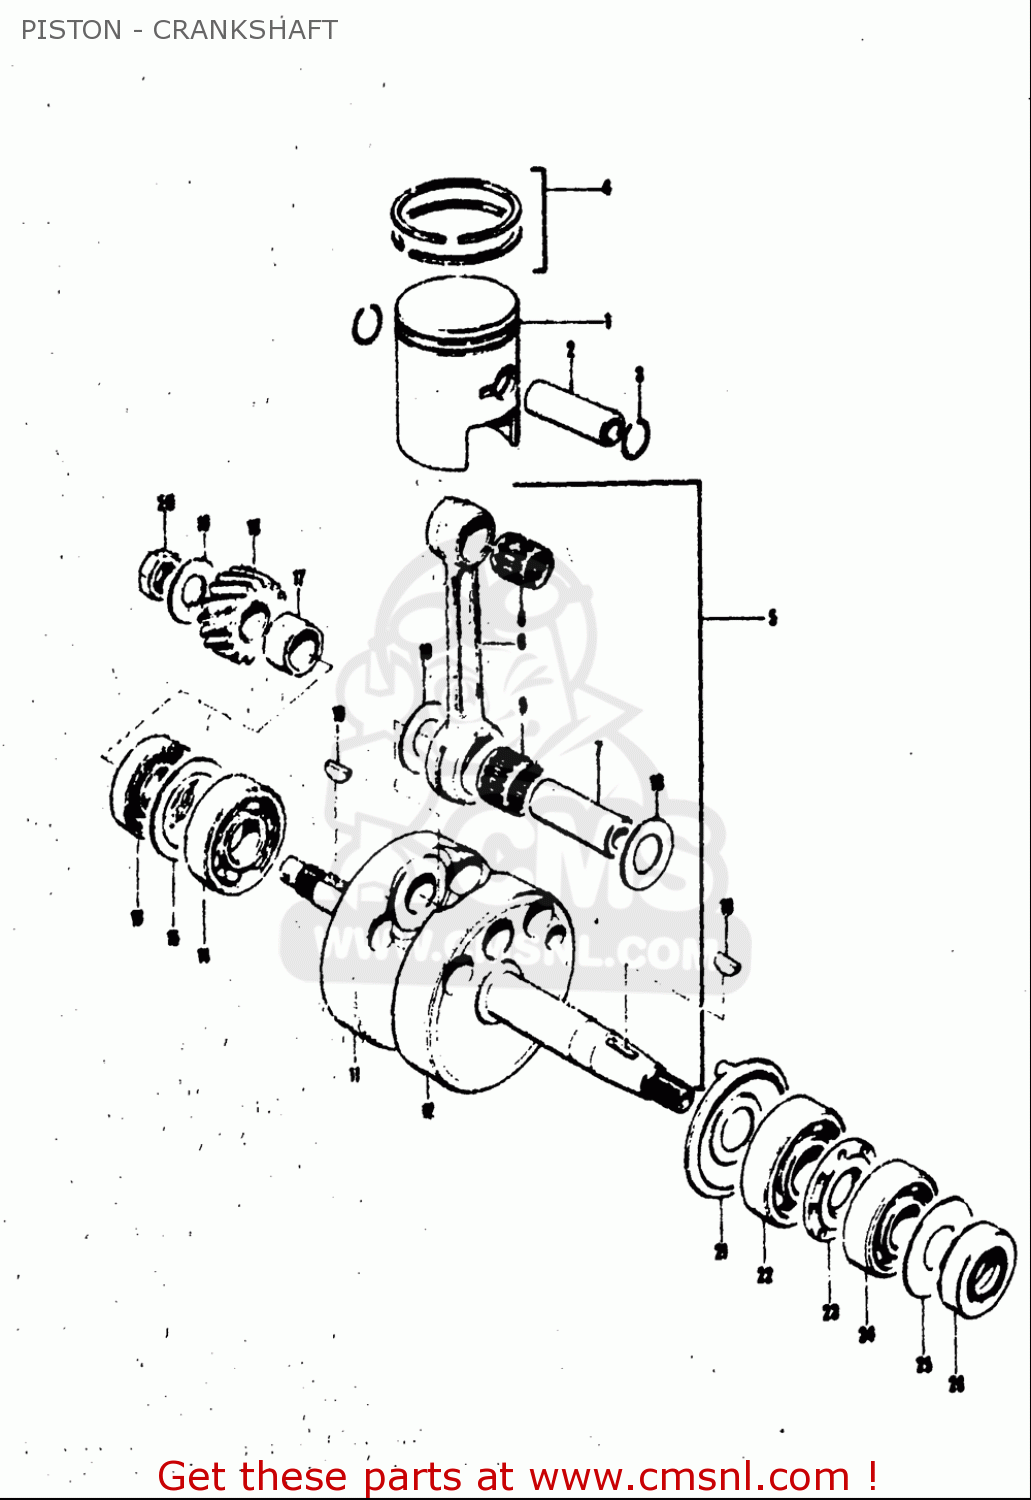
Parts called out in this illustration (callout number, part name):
1	PISTON
2	PIN,PISTON 14MM
3	RING,SNAP 14MM
4	RING SET,PISTON
5	CRANKSHAFT ASSEMBLY
7	PIN,CRANK
8	BEARING(14X18X19.8)
9	BEARING(20X26X16.7)
10	WASHER (20X34X1)
12	CRANKSHAFT,L
13	KEY
14	BEARING(20X52X15)
15	WASHER(41X52X1)
16	SEAL,OIL(26X47X9)
20	NUT
22	BEARING(20X52X15)
24	BEARING(20X47X14)
25	WASHER(34X47X1)
26	SEAL,OIL(20X40X9)
